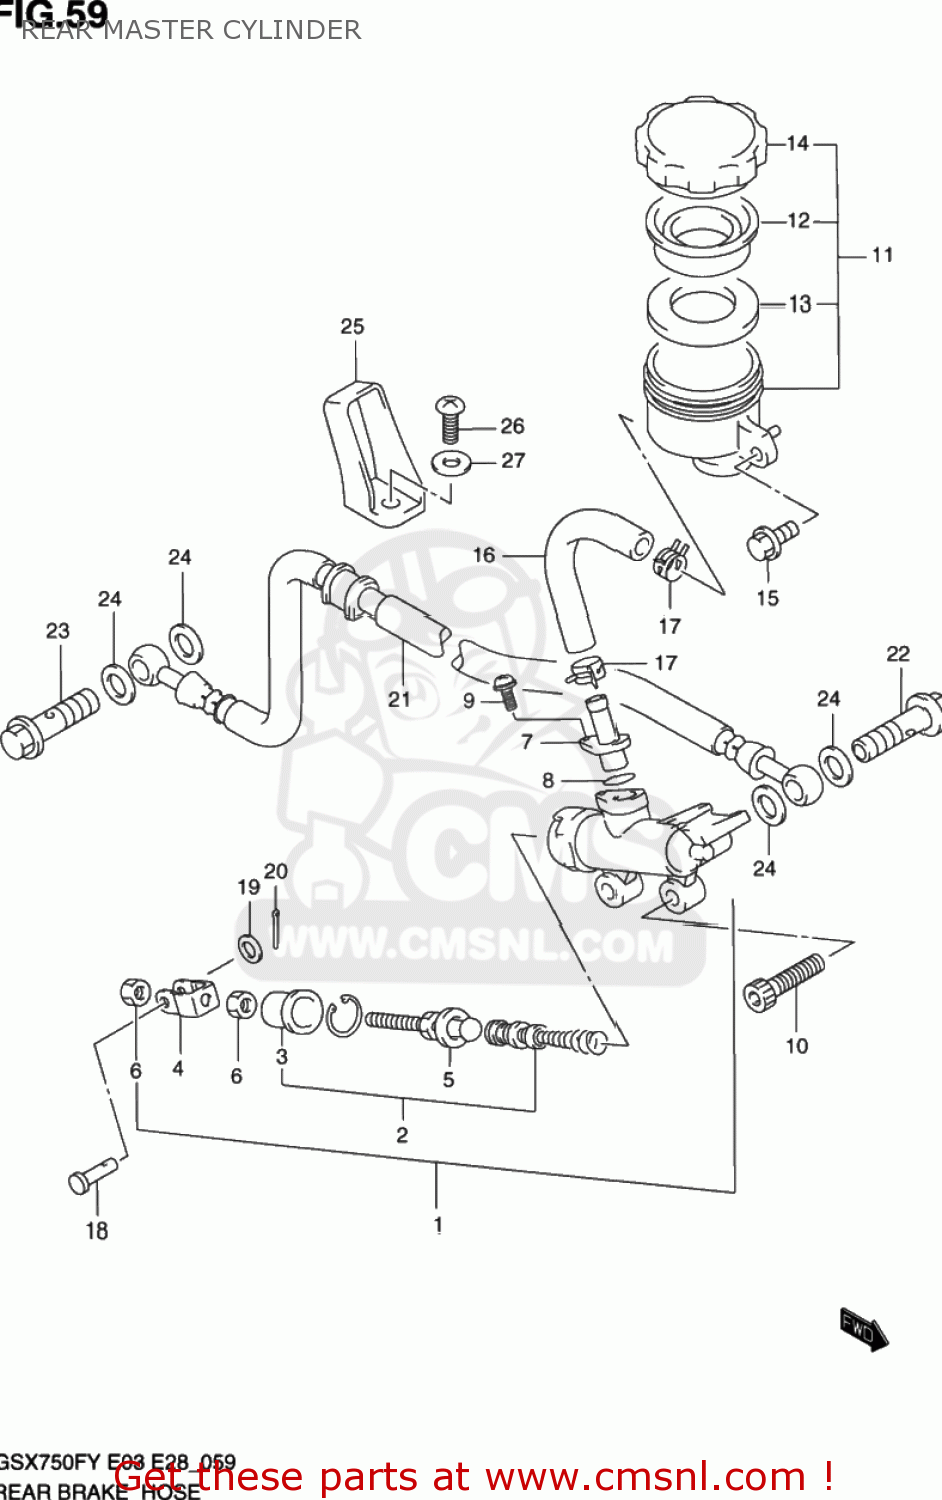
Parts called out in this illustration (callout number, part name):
1	CYLINDER ASSY,RR MASTER
2	PISTON/CUP SET
3	BOOT
4	YOKE
5	ROD,PUSH
6	NUT
7	CONNECTOR
8	O RING
9	SCREW
10	BOLT(6X16)
11	TANK ASSY,RR RESERVOIR
12	DIAPHRAGM
13	PLATE,DIAPHRAGM
14	CAP
15	BOLT
16	HOSE,RESERVOIR TANK
17	CLIP
18	PIN
19	WASHER
20	PIN
21	HOSE COMP,REAR BRAKE
22	BOLT UNION
23	BOLT UNION
24	WASHER(10X15X1.5)
25	GUIDE,RR BRAKE HOSE
26	SCREW
27	WASHER
